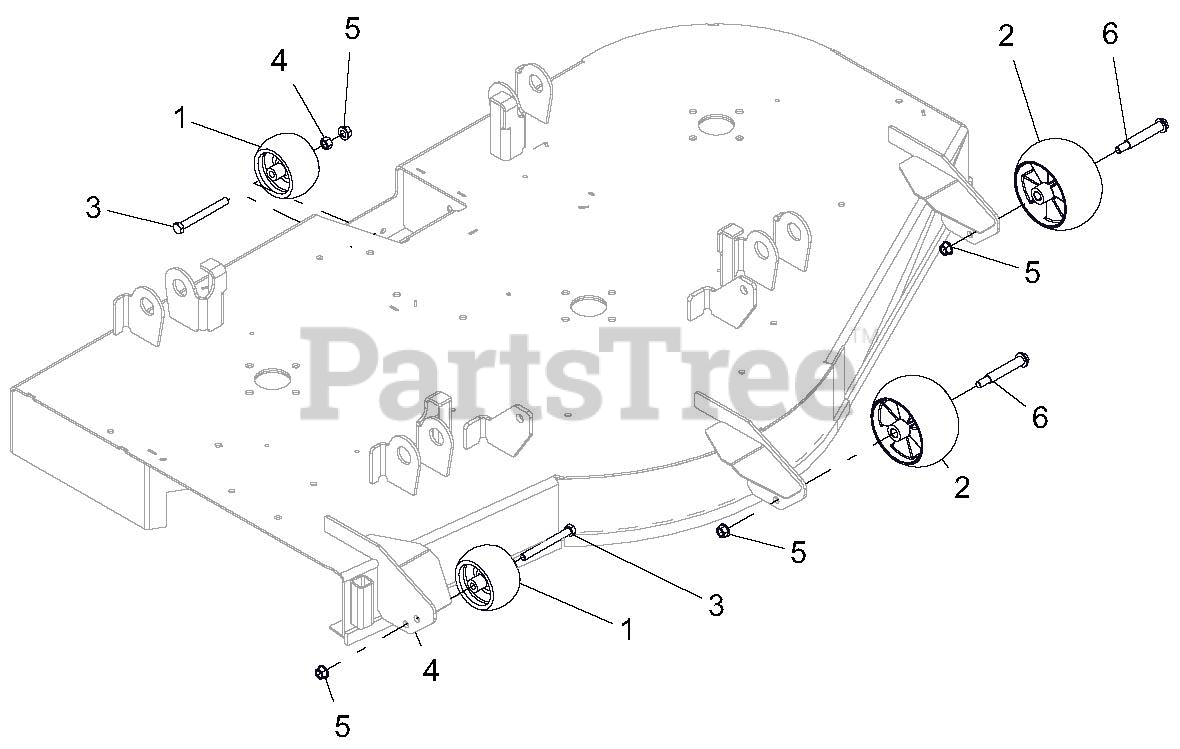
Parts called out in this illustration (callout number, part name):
2	ANTI-SCALP WHEEL - 5X OS
3	@BLT-HEX .38-16X3.50 GR5 YWZC
4	@NUT-HEX .38-16 YWZC
5	@NUT-LK-TOP-FLG .38-16 YWZC
6	BLT-SHLDR .38-16X2.50 HWH G5
